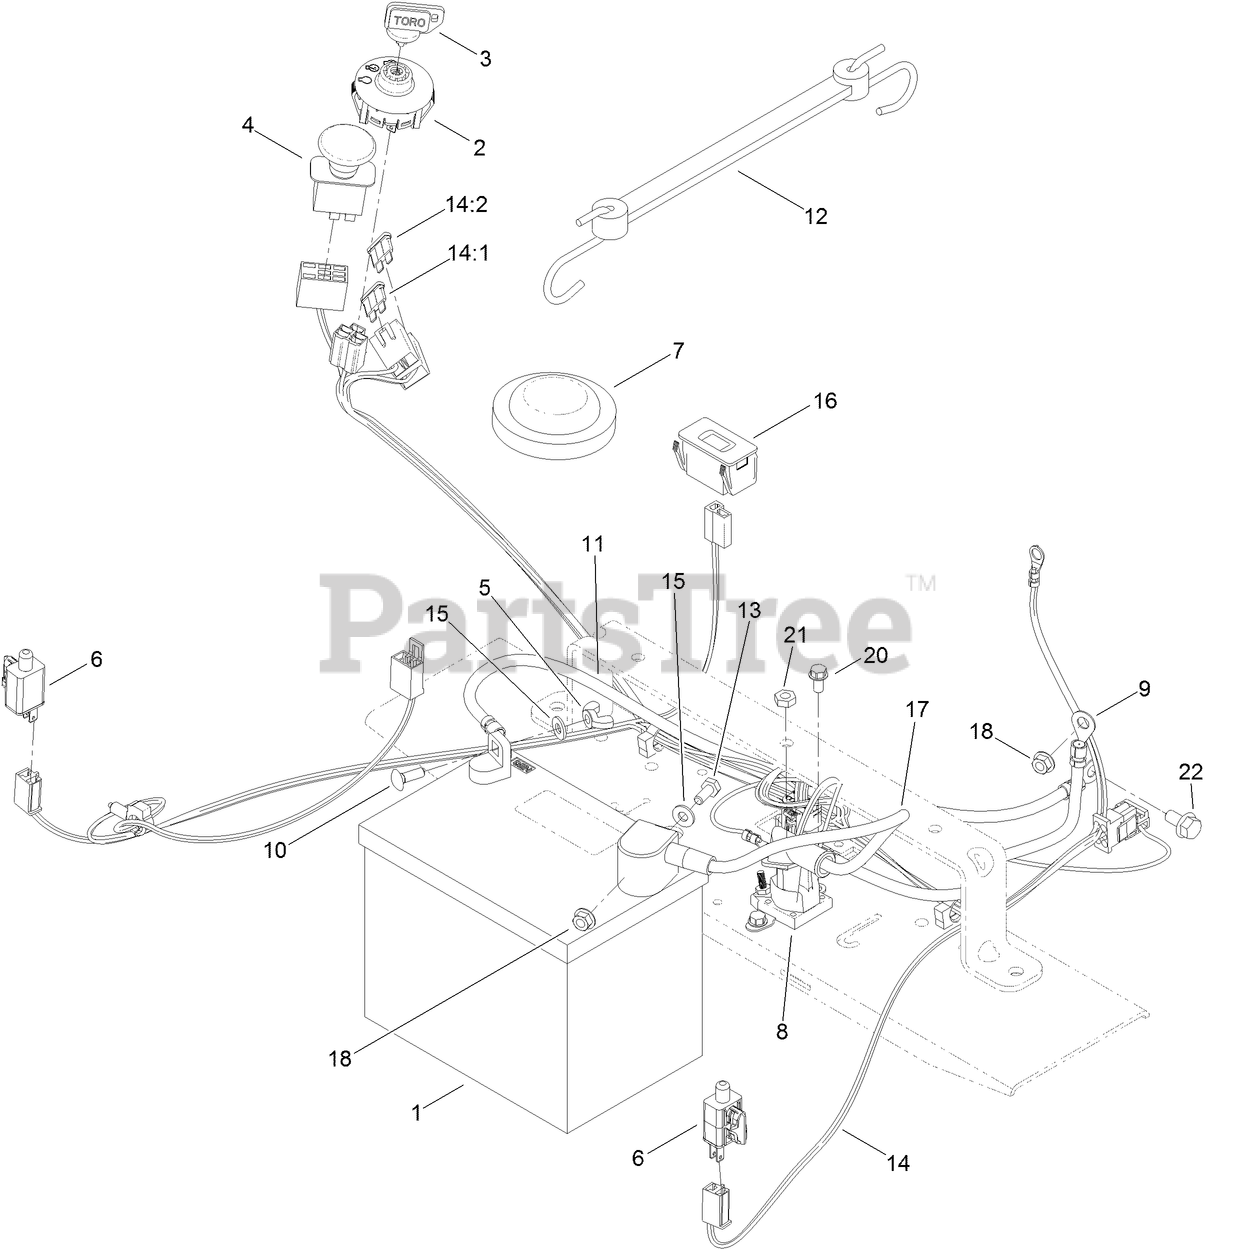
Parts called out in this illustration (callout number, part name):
1	BATTERY
3	KEY-IGNITION
4	SWITCH-PTO
5	NUT-WING
6	SWITCH
7	SWITCH-SEAT
8	SOLENOID
9	CABLE-BATTERY, RED
10	BOLT-CARR
11	CABLE-BATTERY, BLACK
12	HOLDDOWN-BATTERY
13	SCREW-HH
14:1	FUSE-BLADE, 30 AMP
14:2	FUSE-BLADE, 25 AMP
15	WASHER-FLAT
16	HOURMETER
17	CABLE-BATTERY, RED
18	NUT-HF
20	SCREW-HWH
21	NUT-JAM
22	SCREW-HHF
